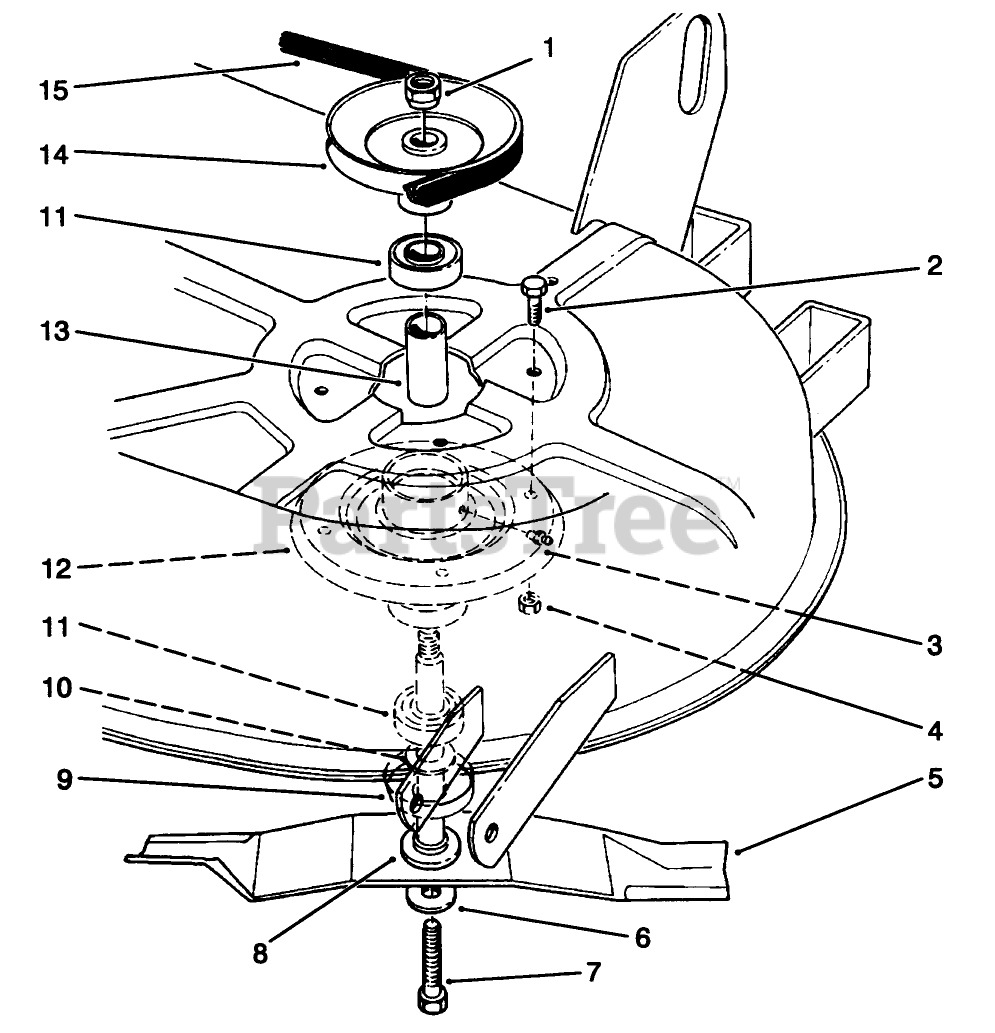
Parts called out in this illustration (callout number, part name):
1	Nut
2	SCREW-HH
3	ZERK FITTING
4	NUT-LOCK, NI
5	Blade
6	WASHER
7	SCREW-HH
8	SHAFT-SPINDLE
9	SHIELD-BEARING
10	SPACER-HARDNED
11	BEARING-BALL
12	HOUSING-SPINDLE (BLACK)
13	SPACER
14	PULLEY
15	V-BELT
